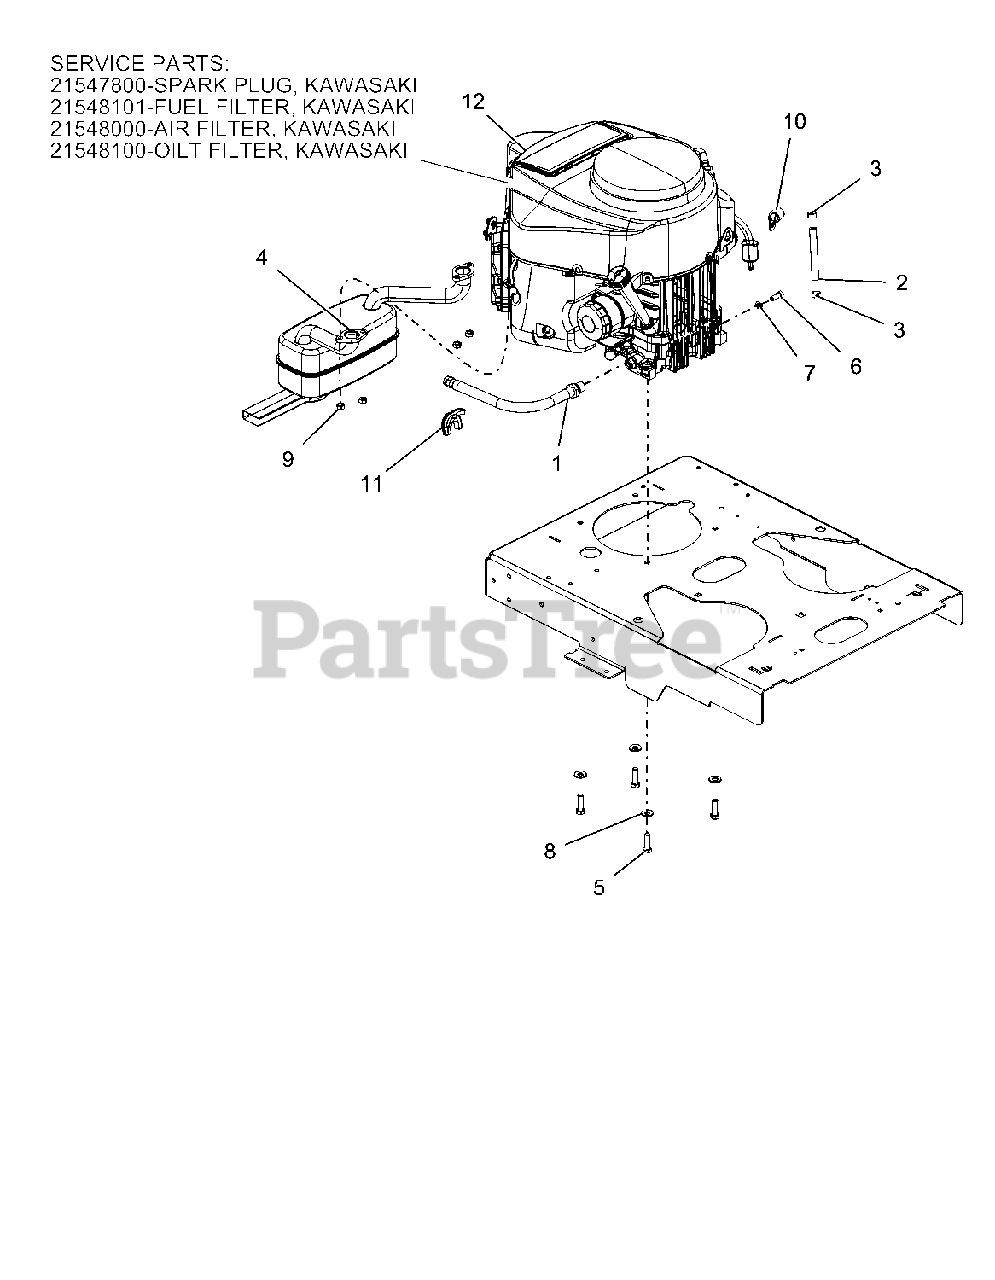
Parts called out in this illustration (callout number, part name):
1	HOSE, OIL DRAIN
2	.25 LOW-PERM GAS HOSE 4.00" LG - TANK TO ENGINE
3	CLAMP, FUEL LINE
4	MUFFLER, KAWASAKI
5	BLT-HEX .38-16X1.25 GR5 YWZC NYTORQ
6	@BLT-HEX M8-1.25X20 YWZC
7	WSHR-LK .31X.078 REG YWZC
8	WSHR, 3/8" SPRING DISC
9	NUT-LK-TOP M8-1.25 YWZC
10	CLAMP, CUSHIONED STEEL .75
11	PROTECTOR, OIL DRAIN HOSE
12	ENGINE, KAWASAKI FR SERIES
12	SPARK PLUG, KAWASAKI
12	FUEL FILTER, KAWASAKI
12	AIR FILTER, KAWASAKI
12	OIL FILTER, KAWASAKI
